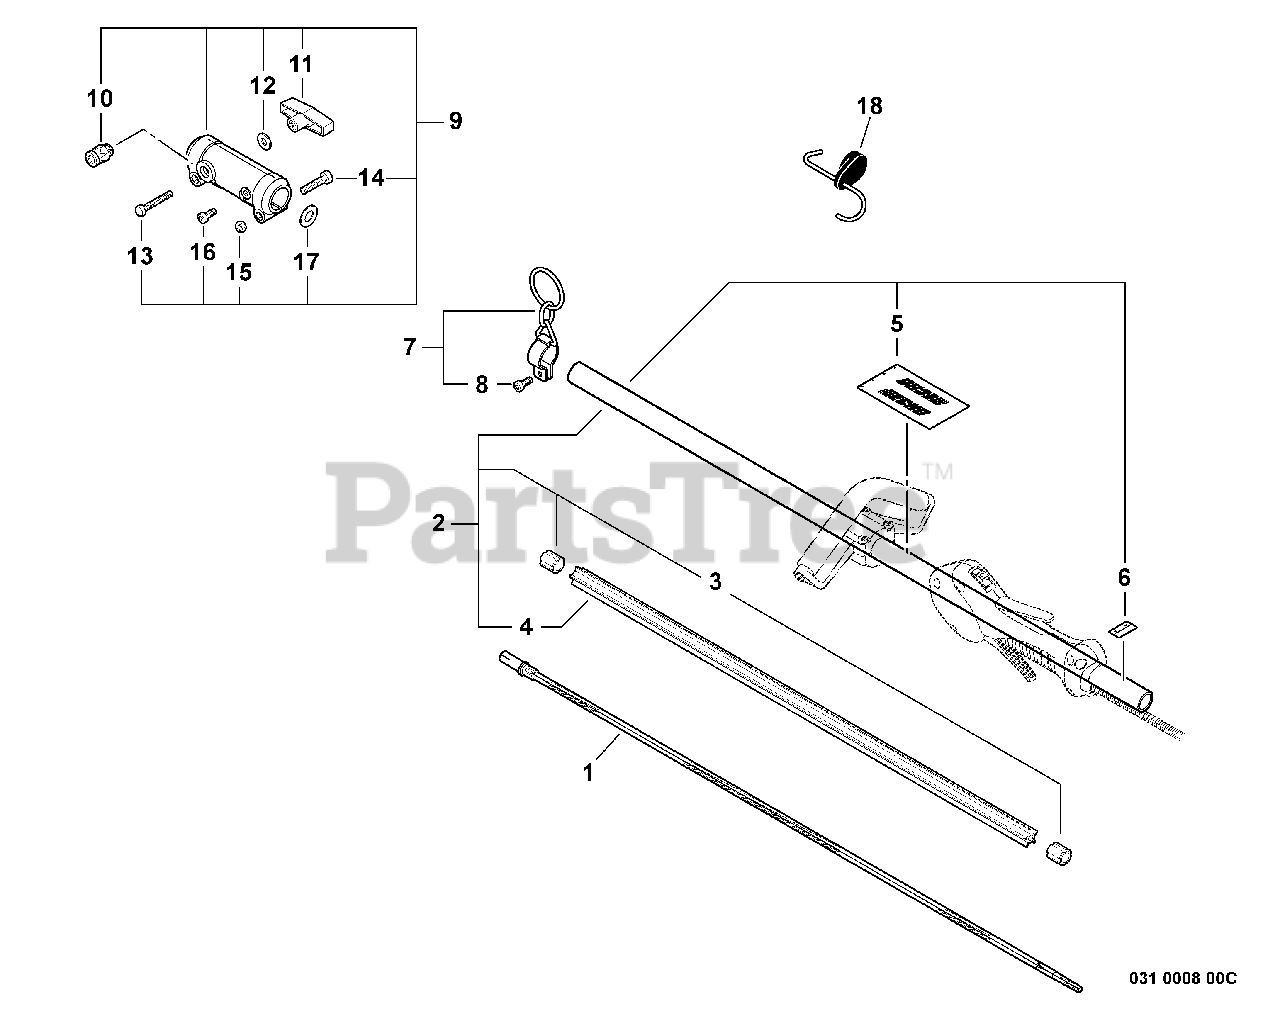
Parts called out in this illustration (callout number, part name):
1	DRIVESHAFT - FLEXIBLE
2	MAIN PIPE ASSY
4	LINER - FLEXIBLE
5	LABEL - HANDLE LOCATION
6	LABEL - ALIGNMENT
7	HANGER KIT
8	SCREW - 5X12
9	COUPLER ASSY
10	LATCH ASSY
11	WINGNUT
12	WASHER - 6
13	BOLT - 6X40
14	SCREW - 6X25
16	SCREW - 5X10
17	WASHER - 18
18	PAS ATTACHMENT HANGER
